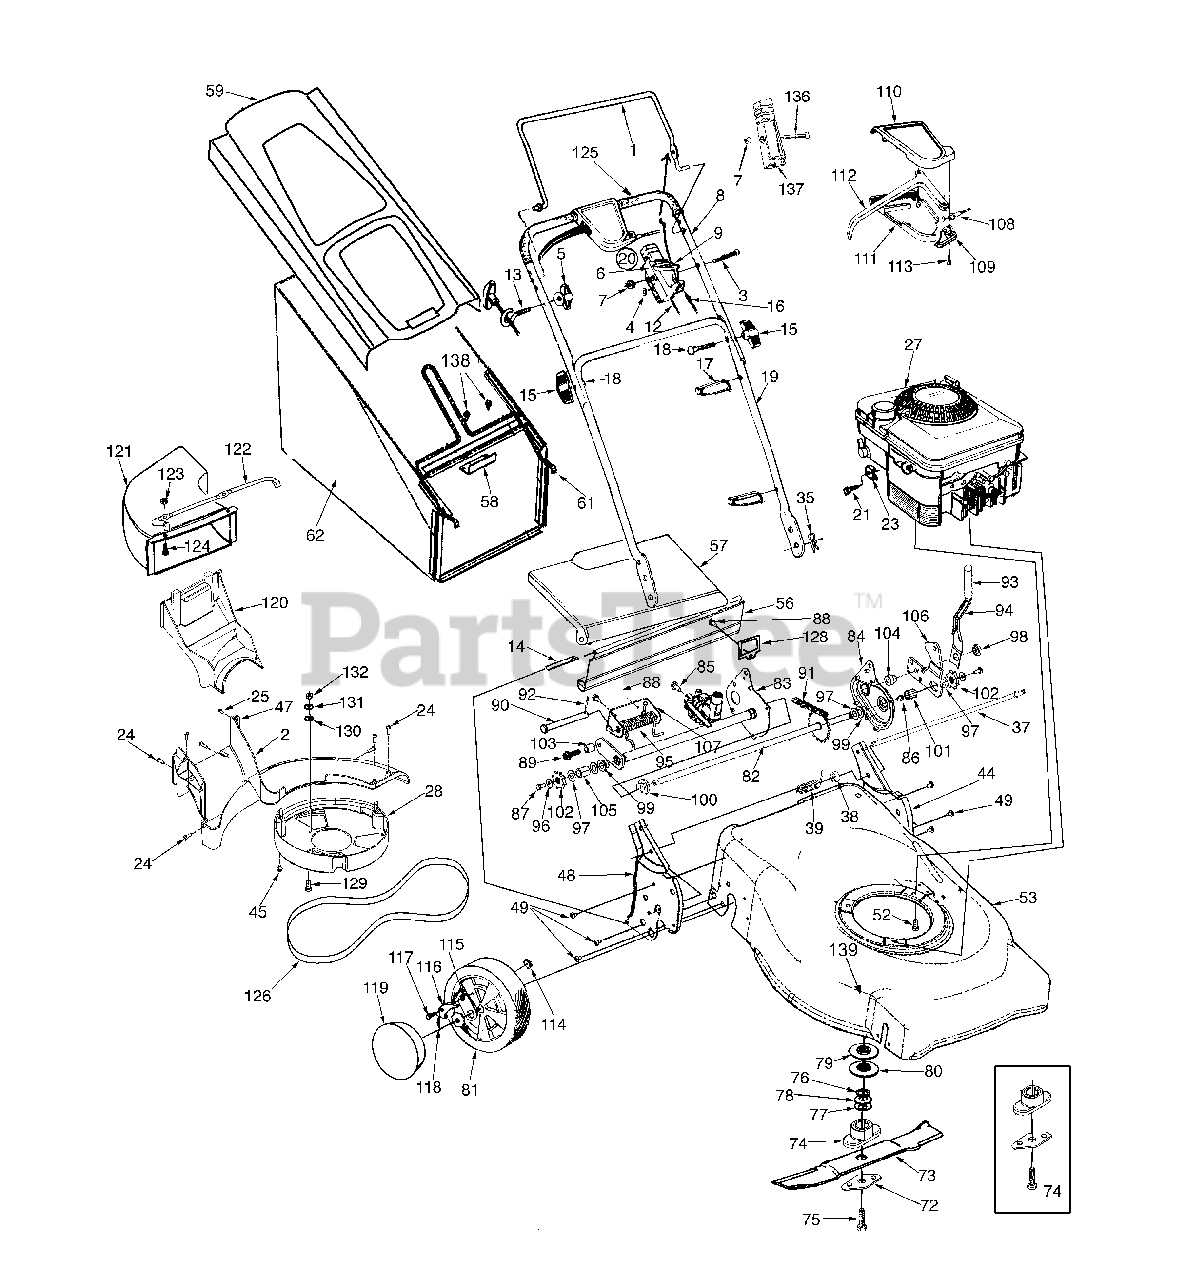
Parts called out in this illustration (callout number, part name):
1	Control Handle Ass'y
3	Oval C-Sunk Mach - Screw
4	Spring Washer .66" ID
5	Handle Knob 1/4-20 Thd.
6	Throttle Body
7	Hex L-Nut 1/4-20
9	Throttle Lever
12	Throttle Control Wire - 47"
12	Throttle Control Wire - 55"
12	Throttle Control Wire - 60"
13	Rope Guide
14	Wire-47" Lg.
15	Hand Knob
16	Control Cable-45"
17	Cable Tie
18	Cr.Hd. Bolt 5 / 16-18 x 2" Lg.
20	Throttle Ass’y (Incl. 3,4,6,7,9)
21	Hex Self-Tap Scr. #10-32 x .62"
21	Hex Sems Scr. #10-32 x .3" Lg.
22	Spark Plug Boot
23	Cable Clamp
24	Screw H.L. 12-24
25	Screw Mach. B Tapp.
28	Belt Cover
35	Int. Cotter Pin 5/15" Dia.
37	Pivot Rod
38	Spacer .385 I.D.
39	Torsion Spring L.H.
52	Hex L-Wash. Hd. Scr. 3/8-16 x 1"
57	Rear Chute Door
58	Brkt. Mtg. Grassbag Black
59	Hardtop Bag Cover
61	Catcher Frame
62	Grass Bag Asm - Cub Cadet
62	Grass Bag - Black
72	Blade Bell Support
73	21" Mulching Blade w/Star
74	Blade Adaptor Kit w/Star
75	Hex Bolt 3/8-24 x 2.5 Lg.
77	Fl. Wash. .885 x 1.85 x .06
78	Spr. Wash. .890 x .7x .04
79	Pulley Half - Upper
80	Pulley Half - Lower
81	Wheel Assembly, Rear
82	Axle Assy: RR
83	Axle Assy: Trans.
84	Cover Ass'y - Chain
85	Scr. TT 5/16-18
86	Scr. TT 1/4-20
87	Hx Cap Screw 1/4-20
88	Hex Washer Screw 1/4-20 x .625
89	Scr 3/8 - 16 x 1.25
90	Pin - Clv. .500 Dia.x.4.62 Lg.
91	Chain:Endless 48:.500P x 22 Lg.
92	Pin-Cotter .125 O.D. x .75
93	Grip-Foam
94	Spring Lever
95	Torsion Spring
96	Bell Washer .265 x .75 x .062
97	Wash.Flat .508 I.D. x 1.0 O.D.
98	Nut - Shoulder .625 x .165 Lg.
99	Bearing-Flg Hex
100	Bearing-Flg. Hex
101	Bearing-Sleeve
102	Ratchet Wheel
103	Spacer - .385 x .625 x .700
104	Spacer-Shld. .385 I.D.x .715 Lg.
105	Spacer Slv. .520 I.D. x .950 Lg.
107	Spring Bracket
108	S.P. Cable 52.5"
109	Control Cable Kit
110	Control Cable Kit
111	Control Cable Kit
113	Screw #10-16 x .625
114	Weld Top L. 1/4-20
115	Pawl Plate
116	Pawl R.H.
117	Shldr. Scr. .340x.285
118	Spring, Ratchet
120	Mulch Plug
121	Chute Deflector
122	Chute Mounting Rod
123	Hex-L-Nut 1/4-20 thd.
124	Mach. Scr. 1/4-20
125	Foam Grip
129	Scr. TT 1/4-20:1.750 Hx Ind Wash
130	Lockwasher 1/4" Reg.
131	Fl. Wash. .271 x .630 x .065
132	Nut 1/4-20
136	Scr. 1/4-20:1.31 Lg.
137	Housing (w/o Throttle)
138	Hex Washer Screw 1/4-20 x .625
